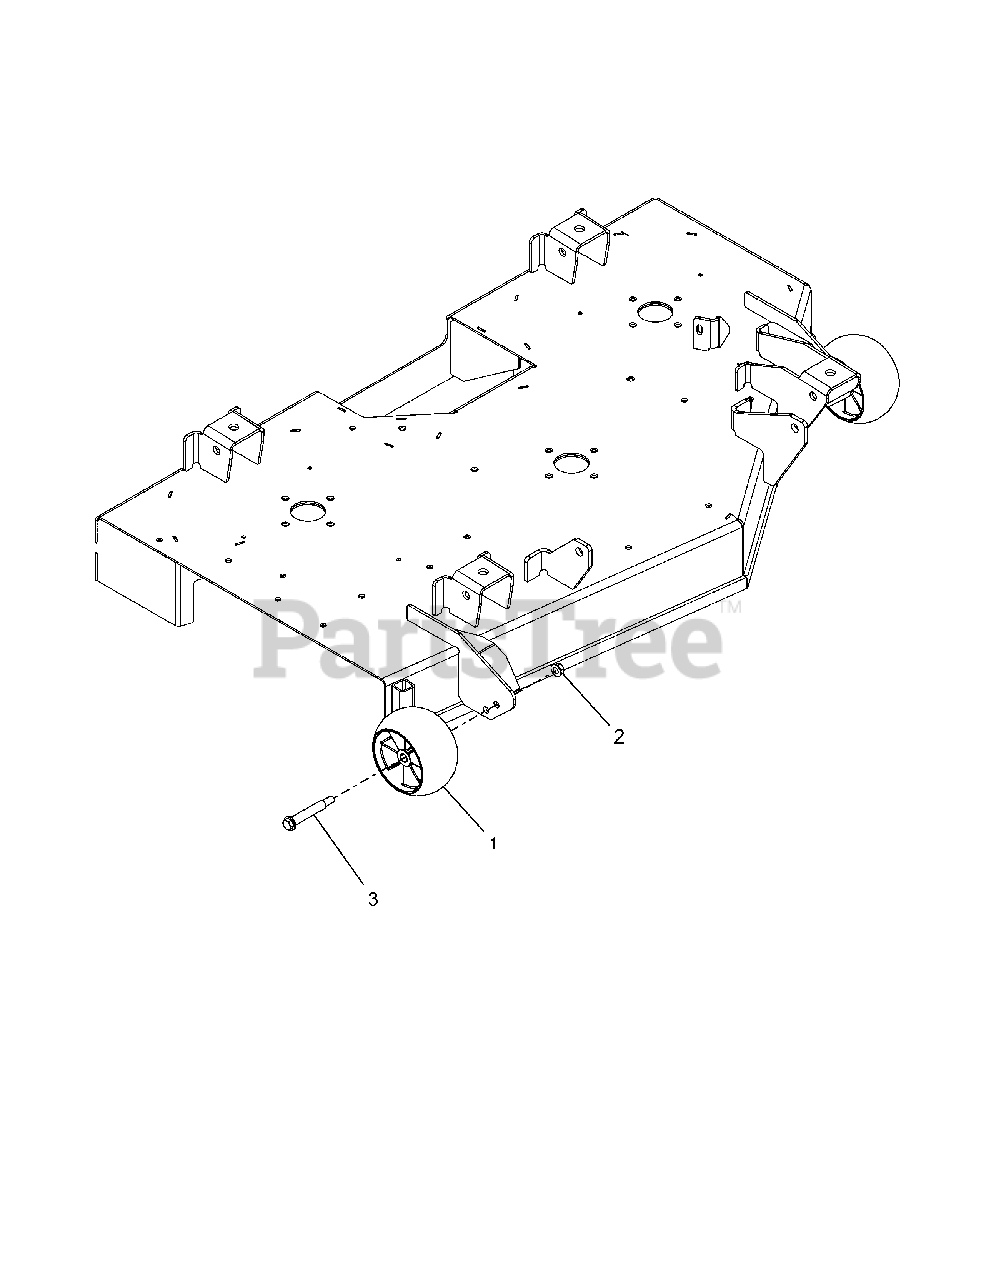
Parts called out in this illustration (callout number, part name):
1	ANTI-SCALP WHEEL - 5X OS
2	NUT-LK-TOP-FLG .38-16 ZC120
3	BLT-SHLDR .38-16X2.50 HWH G5
